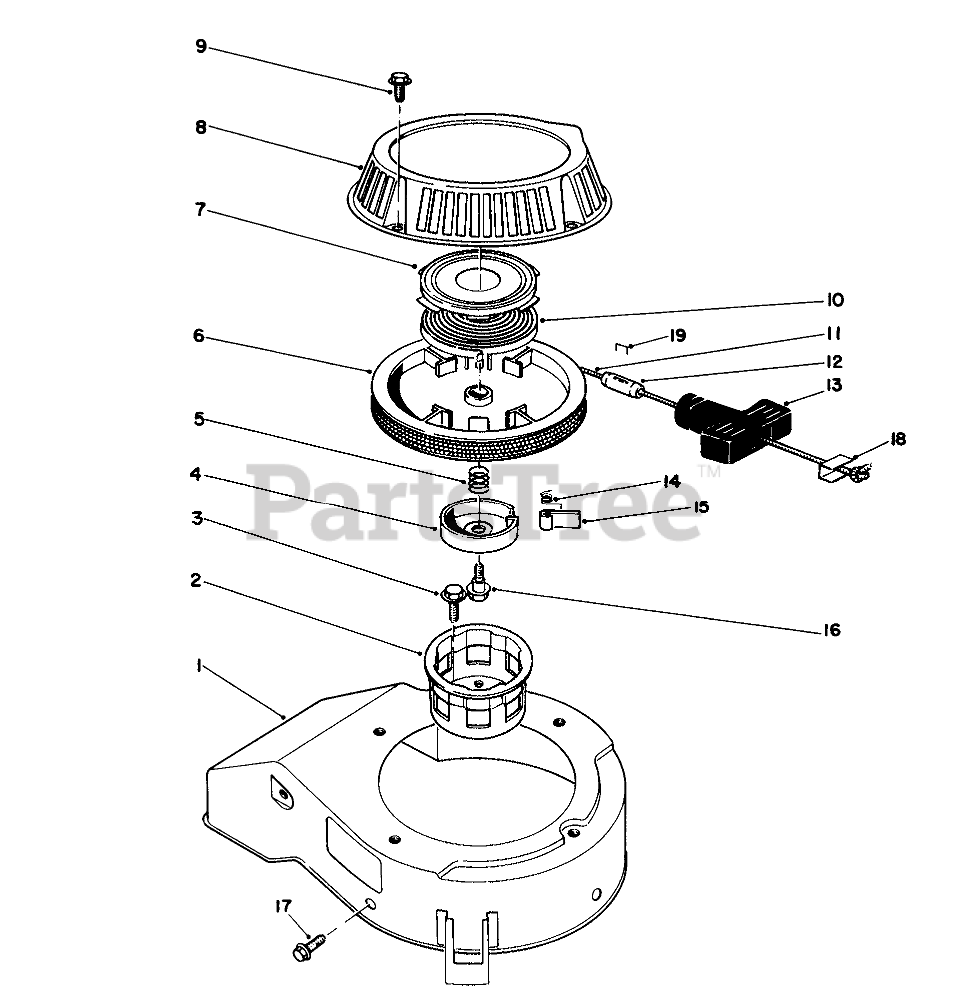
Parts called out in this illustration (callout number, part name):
1	COVER
2	CUP - STARTER
4	RETAINER
5	SPRING
7	Retainer Cup-Recoil Spring
9	SCREW-HHF
10	Spring-Recoil
11	ROPE-STARTER
13	HANDLE-RECOIL
14	SPRING
18	Insert Handle
19	STAPLE
